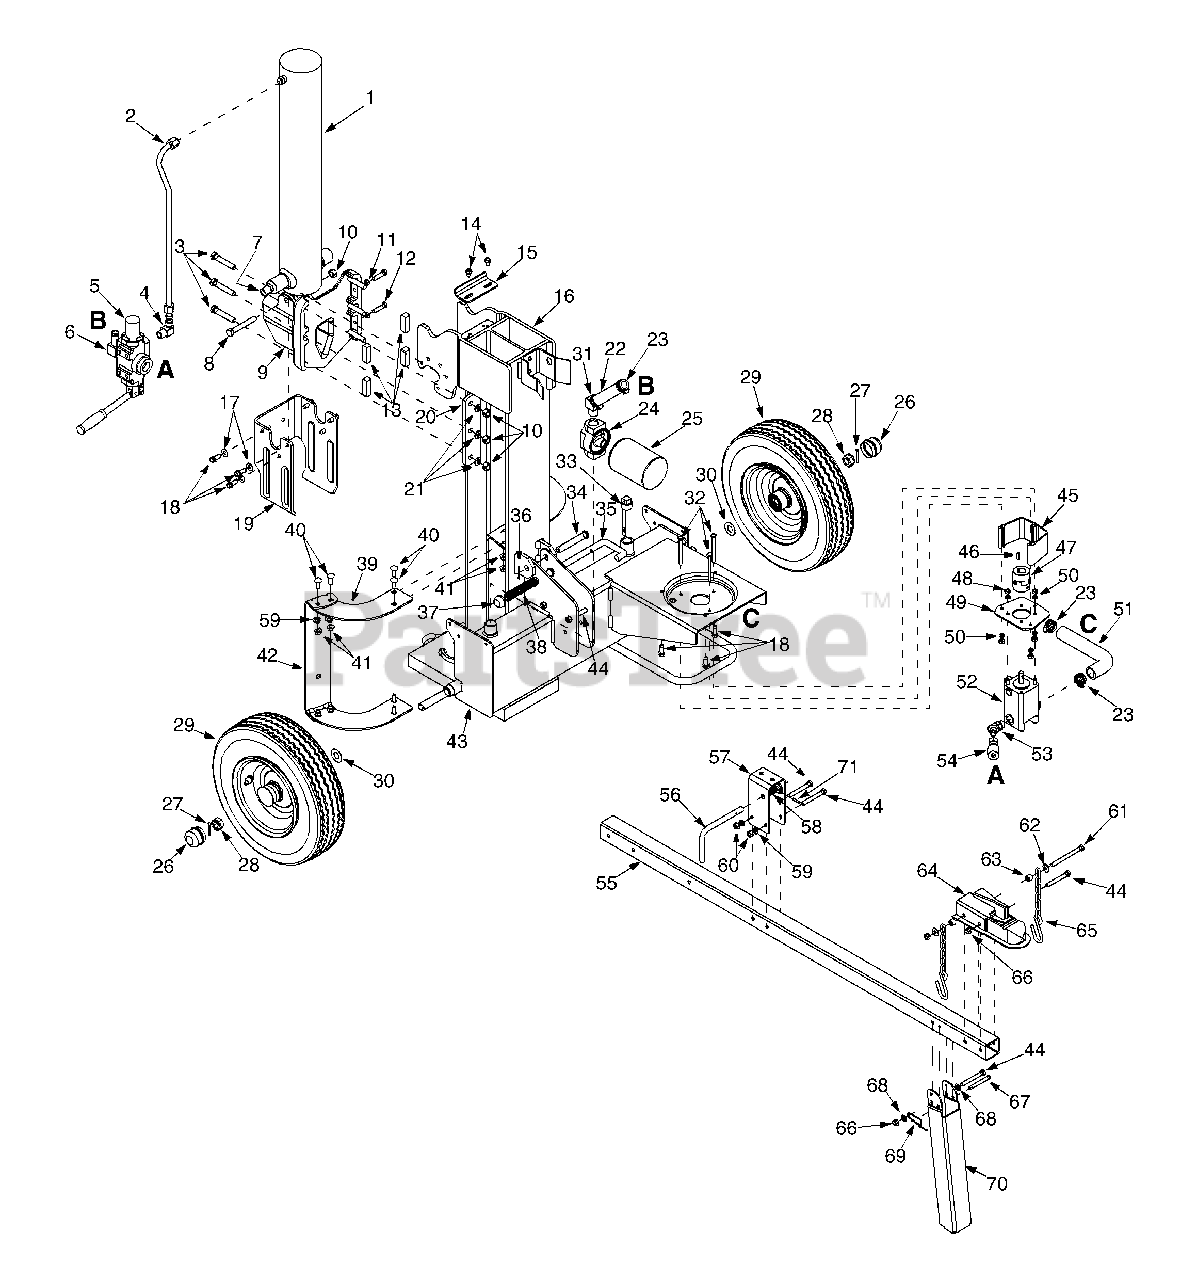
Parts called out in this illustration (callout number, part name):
1	Hydraulic Cylinder
2	Hydraulic Tube
3	Hex Cap Screw 1/2-20 x 2.75
4	90 Degree Solid Adapter
6	Return Elbow
7	Nipple Pipe 1/2-14
8	Hex Cap Screw 1/2-20 x 3.50
9	Wedge Assembly
10	Lock Nut 1/2-20
11	Hex Jam Nut 3/8-24
12	Hex Cap Screw 3/8-24 x 1.5
14	Hex Washer Screw 5/16-18 x .625
17	Flat Washer .406 ID x .875 OD
18	Hex Washer Screw 3/8-16 x 1.0
21	Lock Washer 1/2
22	Return Hose 3/4" ID x 44" Lg.
23	Hose Clamp 5/8"
24	Filter Housing
25	Oil Filter
26	Hub Cap
27	Cotter Pin
28	Slotted Nut 3/4-16
29	Wheel Assembly
30	Flat Washer .760 ID x .500 OD
31	Adapter 3/4-14
32	Hex Screw 5/16-24 x 3.25
33	Vented Dipstick
34	Clevis Pin
35	Lock Rod
36	Cotter Pin
37	Push Cap
38	Compression Spring
41	Hex Nut 3/8-16
43	Frame Assembly
44	Hex Bolt 3/8-16 x 3"
45	Coupling Shield
46	Square Key 3/16" x .75
47	Flexible Coupling .750 x .500
47	Flexible Coupling .875 x .500
47	Flexible Coupling .875 x .437
48	Hex Nut 5/16-24
50	Lock Washer 5/16" ID
52	Gear Pump (11 gpm)
52	Pump Kit
52	Gear Pump (9.5 gpm)
53	45 Degree Elbow
54	High Pressure Hydraulic Hose
56	Latch Rod
58	Spring Compression
59	L-Washer 3/8"
60	Hex Nut 3/8-16
61	Hex Cap Screw 3/8-16 x 4.25
62	Flat Washer .385 ID x .870 OD
63	Spacer .375 ID x .625 OD
64	Coupling Hitch
65	Chain
66	Hex Lock Nut 3/8-16
67	Clevis Pin
68	Flat Washer .375 ID x .738 OD
69	Spring Pin
